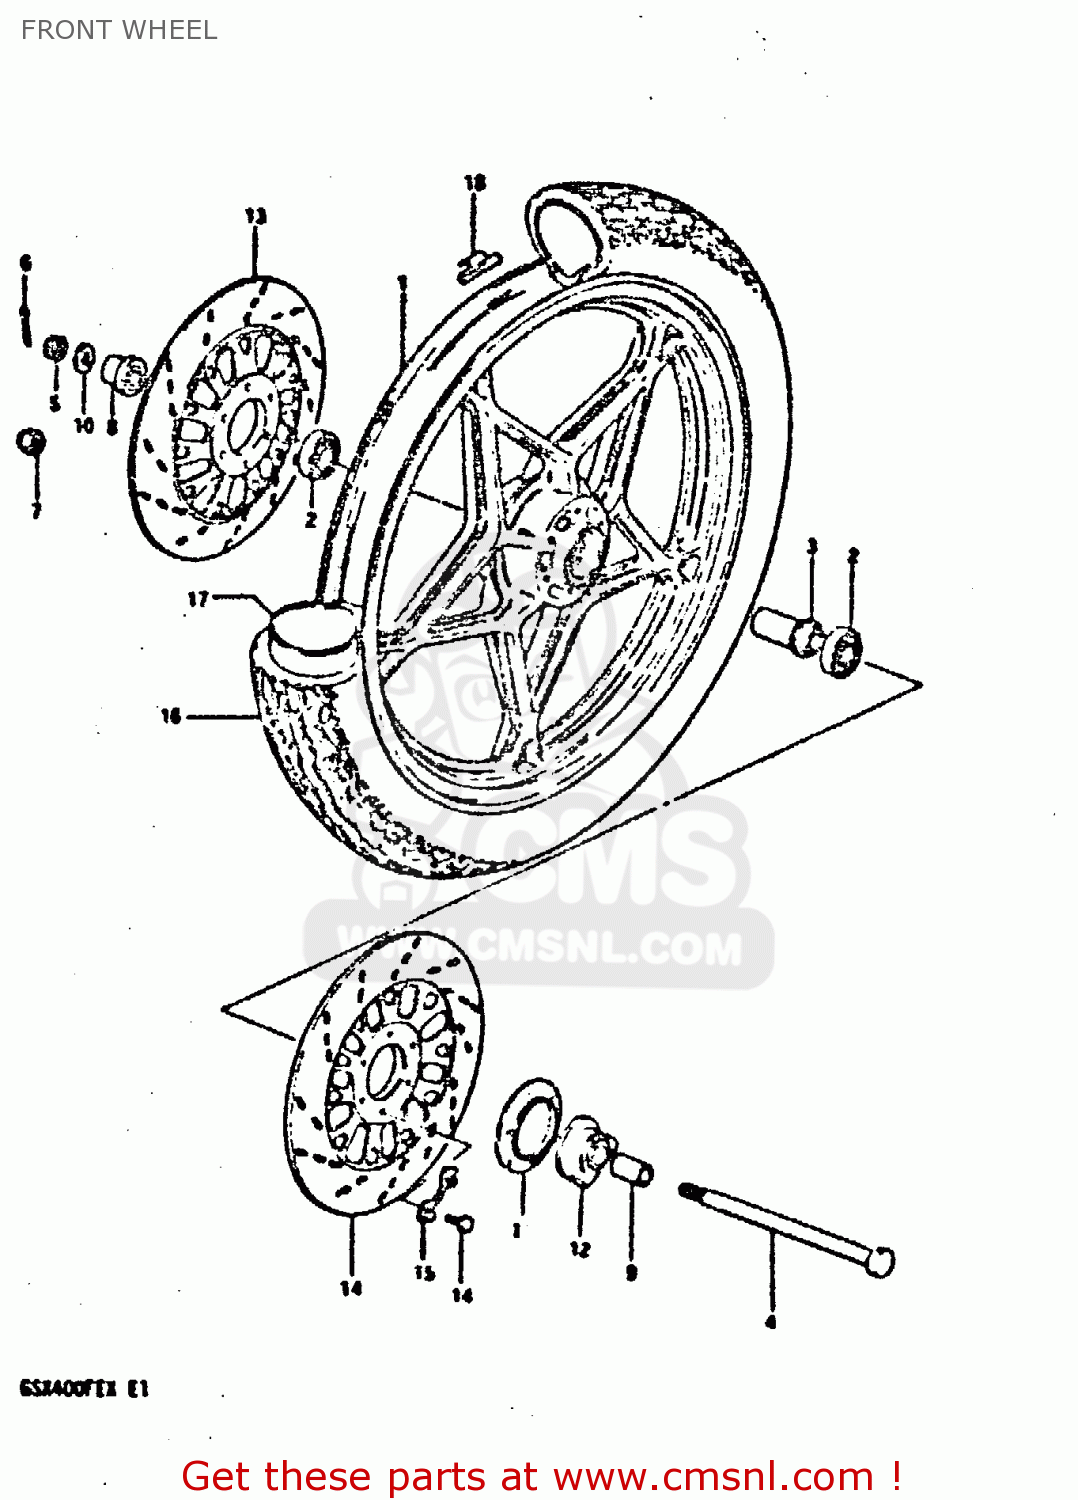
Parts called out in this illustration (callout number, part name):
1	WHEEL, FRONT (1.85-19)
2	BEARING
3	SPACER,FR HUB BEARING
4	AXLE,FRONT
5	NUT
6	COTTER PIN
8	SPACER,FR HUB BEARING,R
9	SPACER(15X22X30)
10	WASHER
11	DUST SEAL,SPEEDOMETER GEAR BOX
12	BOX ASSY, SPEADEMETER GEAR
13	DISK, FRONT BRAKE
14	BOLT(8X25)
15	WASHER
16	TIRE (3.25S19)
17	TUBE,INNER
18	BALANCER,WHEEL
